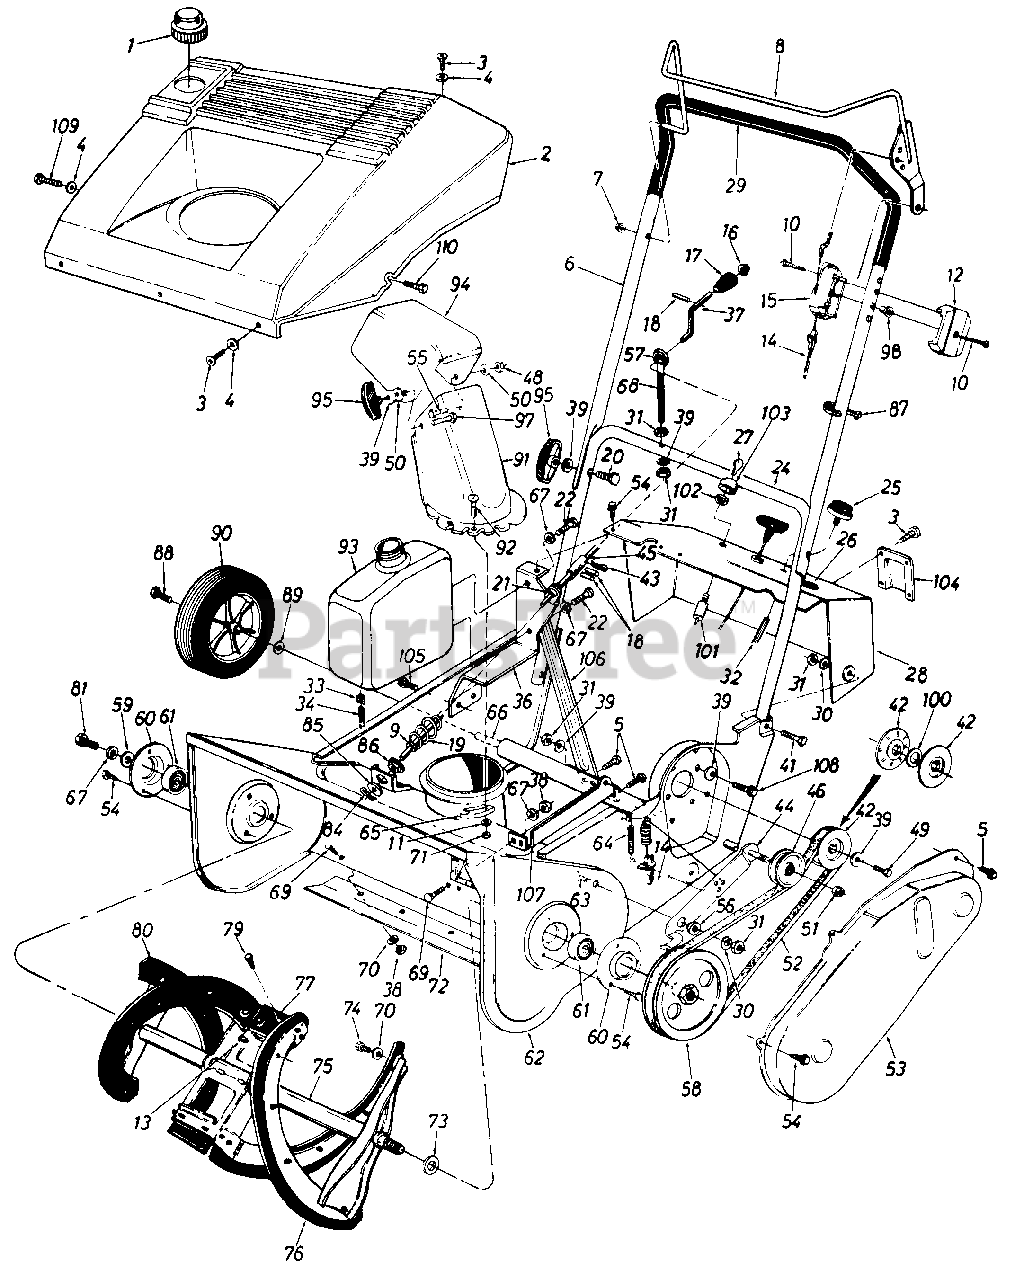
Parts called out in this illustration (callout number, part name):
1	Gas Tank Cap
3	Hex B-Tap Scr. #10 x .5" Lg.
4	Fl-Wash. .203" I.D. x .41"
5	Hex L-Wash. Hd. AB-Tap 1/4 x.62" Lg.
8	Control Handle Ass'y.-L.H.
9	Fl-Wash. .385" I.D. x .62"
10	Truss Mach. Hi-B Tap Scr. #12 x 1.5" Lg.
11	Fl-Wash. .281" I.D. x .5" O.D.
12	Control Panel Half
13	Pop Rivet .188" Dia.
14	Clutch Cable 35" Lg.
15	Control Panel Half
16	Push Cap 318" Rod
17	Knob-318" Dia. Hole
18	Roll Pin 118" Dia. x .63" Lg.
19	Lower Chute Crank Ass'y.
20	Curved Carriage Bolt 5/16-18 x 1.75" Lg.
21	Chute Crank Grommet
22	Hex Bolt 1/4-20 x .5" Lg.
26	Plastic Plug
30	L-Wash. 5/16 I.D.
31	Hex Nut 5/16-18 Thd.
32	Primer Hose-9" Lg.
33	Hose Clamp-1/2" O.D.
34	Gas Line-16" Lg.
36	Gas Tank Support Brkt.
38	Hex Jam Nut 1/4 - 20 Thd.
39	Bell-Wash. .345" I.D. x .88"
41	Hex Bolt 5/16 - 18 x 1.5" Lg.
42	3/8" "V"-Pulley Half .625" I.D. x 6.0" O.D.
43	Cotter Pin 3/32" Dia. x 1" Lg.
44	Idler Brake Brkt. Ass'y
45	Spacer .38" I.D. x 1.12" Lg.
46	Fl-Idler w/Flanges 2.12" O.D.
48	Hex L-Nut 5/16 - 18 Thd.
49	Hex Bolt 5/16 - 24 x .75" Lg.
50	Fl-Wash. .344" I.D. x 1.25"
51	Hex Patch L-Nut 3/8 - 24 Thd.
52	"V" - Belt
54	Hex B-Tap Scr. 1/4" x .38" Lg.
55	Carriage Bolt 5/16 - 18 x .75"
56	Shld. Spacer .50" Dia. x .27"
57	Plastic Bushing .38" I.D.
58	1/2" "V" - Pulley 1/2 - 2 L.H. x 6"
59	Fl-Wash. 1/4" I.D. x .93" O.D.
64	Extension Spring 1.12" Lg.
65	Chute Flange Keeper
66	Wheel Axle 20.6" Lg.
67	L-Wash. 1/4" I.D.
69	Carriage Bolt 1/4 - 20 x .50"
70	Fl-Wash. .281" I.D. x .73"
71	Hex L-Nut 1/4 - 20 Thd.
72	Shave Plate
73	Fl-Wash. .510" I.D. x 1.0" O.D.
74	Hex Wash. B-Tap Scr. 1/4 x .62" (Spec)
76	Rubber Spiral-L.H.
77	Rubber Paddle
79	Hex Wash. B-Tap Scr. #10 x .62" Lg.
80	Rubber Spiral-R.H.
81	Hex Wash. TT-Tap Cl-Scr. 1/4 - 20 x .75" Lg.
84	Cotter Pin 3/32" Dia x .75"
85	Fl-Wash. .406" I.D. x 1.25"
86	Hex Bushing .385" I.D.
87	Cable Tie
88	Hex Tap Scr. 3/8 - 24 x .88" Lg.
89	Fl-Wash. .510" I.D. x .75"
90	7" Wheel & Tire Ass'y.
91	Lower Chute
92	Truss Mach. Scr. 1/4 - 20 x .75"
93	Fuel Tank-Two Qt.
94	Upper Chute
95	Knob Handle Ass'y.
97	Carriage Bolt 5/16 - 18 x 1"
98	Control Disc Pin
100	Fl-Wash. .635" I.D. x .93" O.D.
101	Key Switch
102	Ignition Switch Nut 5/8 - 32 Thd.
103	Ignition Switch Cap
104	Choke Cover
105	Hex Wash. Hd. Tap Scr. 1/4 - 5" Lg.
108	Hex Bolt 5/16 - 18 x 5/8" Lg.
109	Pan Hd. Tap Scr. #10 x 1.25" Lg.
110	Hex Wash. Hd. Tap Scr. 1/4 - 20 x 1" Lg.
